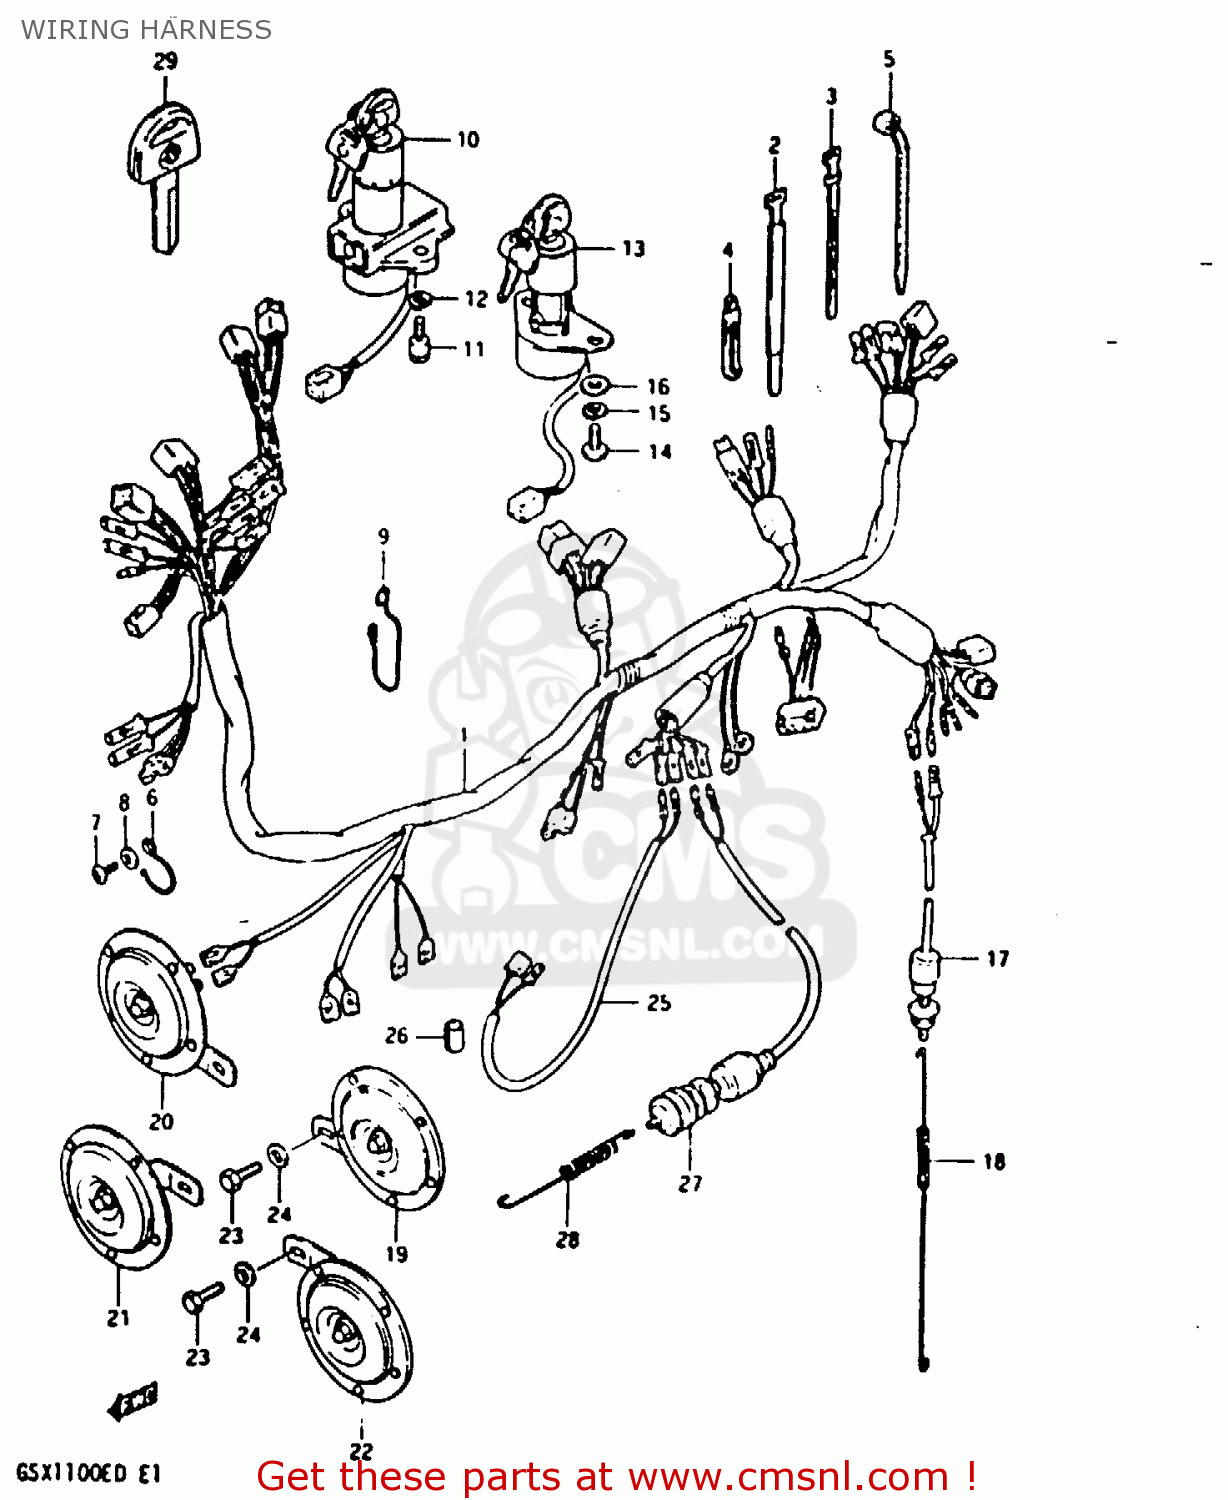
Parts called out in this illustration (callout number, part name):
1	HARNESS,WIRING
2	CLAMP
3	CLAMP(L:120)
4	CLAMP
5	CLAMP(L:95)
6	CLIP,WIRING HARNESS
7	SCREW 6X12
8	WASHER
9	BOOT,WIRING HARNESS
10	SWITCH ASSY,IGNITION
11	BOLT
12	LOCK WASHER
17	SWITCH ASSEMBLY,STOP LAMP
18	SPRING
19	HORN ASSEMBLY,LOW PITCH
20	HORN ASSEMBLY,HIGH PITCH
21	HORN ASSEMBLY,LOW PITCH
22	HORN ASSEMBLY,HIGH PITCH
23	BOLT 8X12
24	WASHER
25	WIRE
26	CLIP
27	SWITCH ASSEMBLY,SIDE STAND
28	SPRING
29	KEY,BLANK
